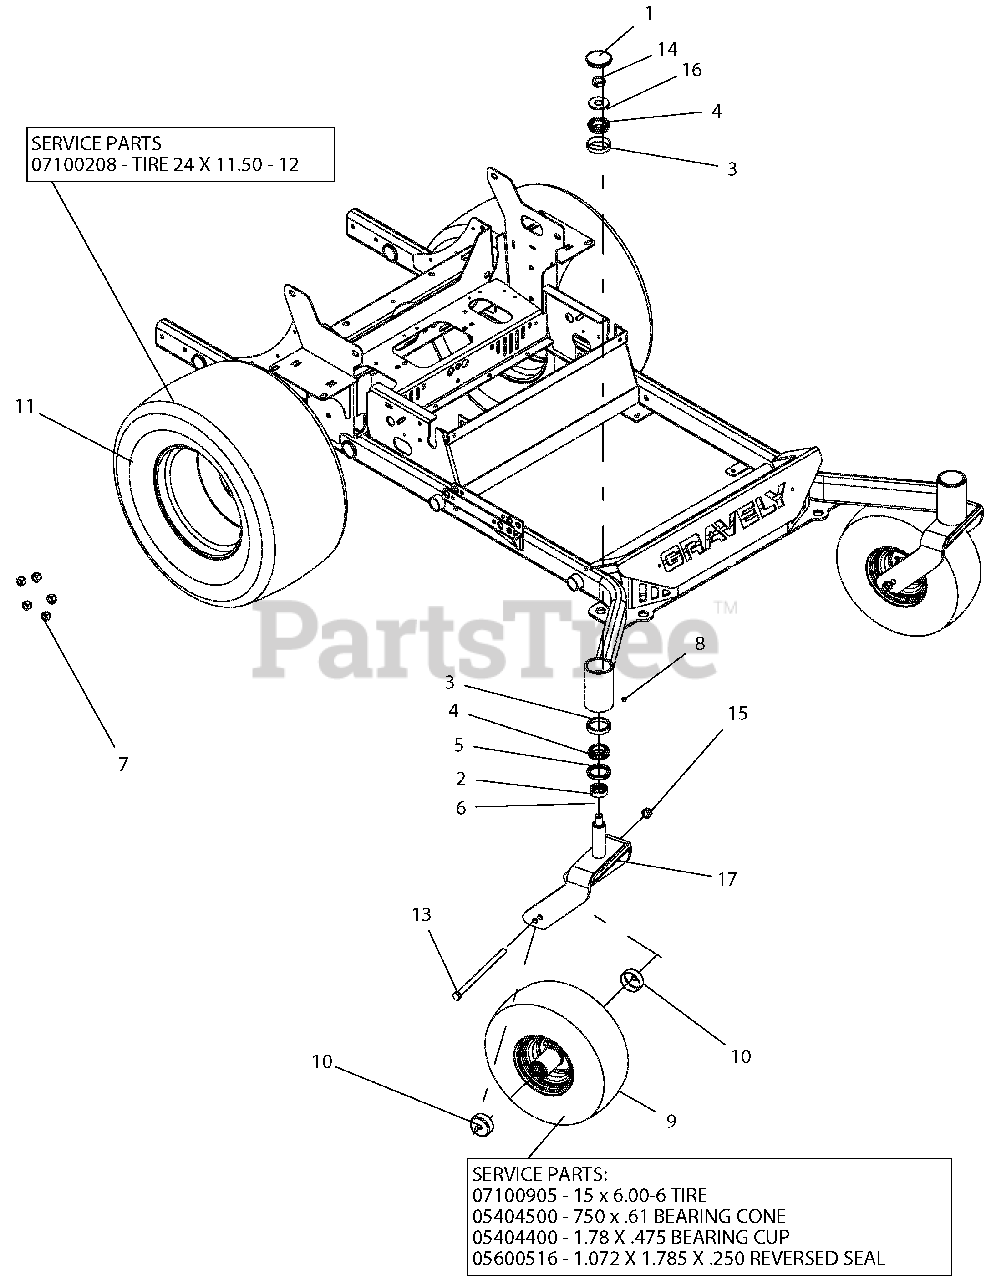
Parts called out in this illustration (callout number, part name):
1	CAP, DUST
2	SPCR, FRONT CASTER FORK
3	BRG, CUP 2.328 X .465
4	BRG, CONE 1.250 X .660
5	SEAL, OIL 1.75 X 2.332 X .312
6	O-RING, .139 W X 1.234 ID
7	NUT, LUG .500-13
8	PLUG, .250-28 X .185 HEX HEAD
9	TIRE/WHEEL, 15 X 6.00-6 SMOOTH
10	SHIELD, WHEEL BEARING
11	TIRE/WHEEL, ASM 24X11.50-12
13	BLT-HEX .50-13X9.00 GR5 YWZC
14	@NUT-LK-CTR-JAM .75-16 YWZC
15	NUT, LK-TOP-FLG .50-13 YWZC
16	WSHR-FL-STL.812X2.00X.148YWZC
17	WMT, CASTER FORK - RED
